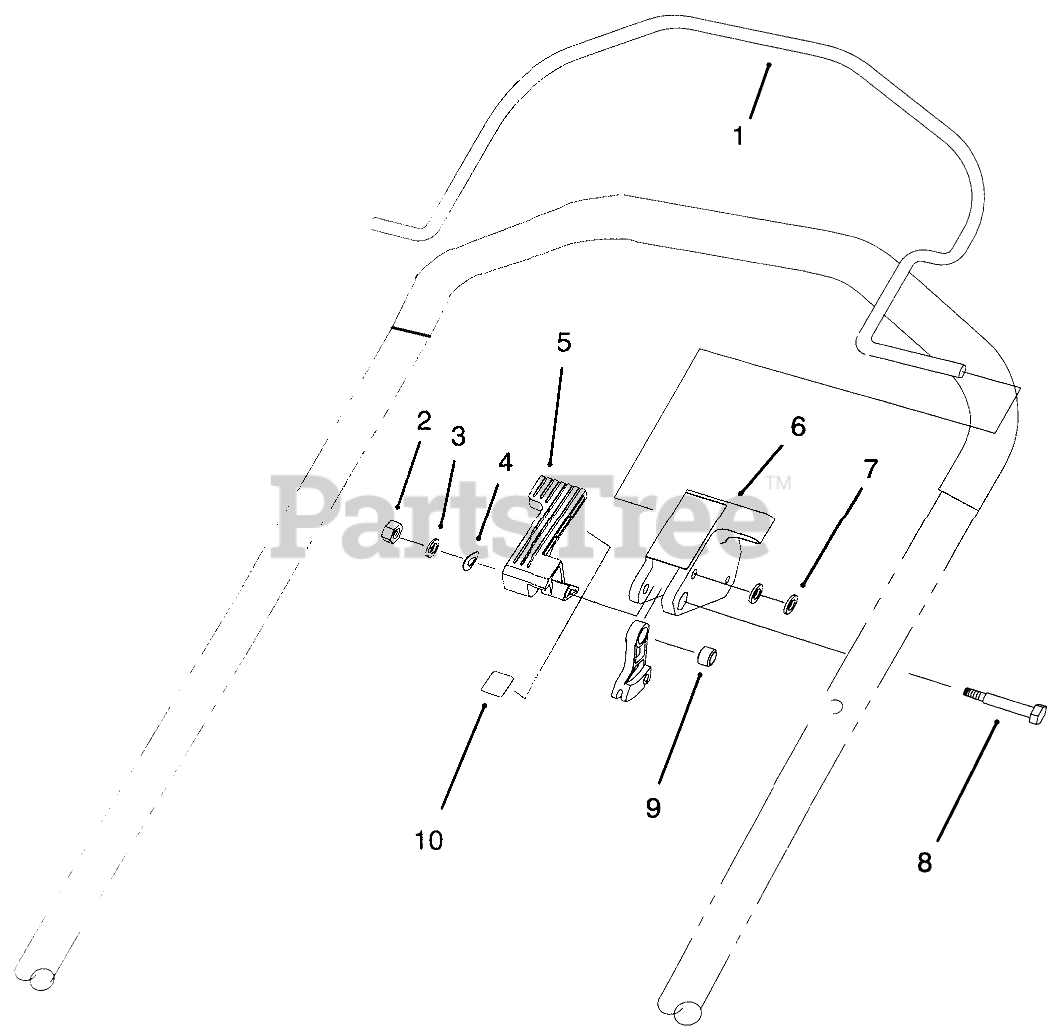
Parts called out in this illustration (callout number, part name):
1	BAIL - CONTROL
2	NUT-LOCK, NI
3	WASHER-PLAIN
4	WASHER - SPRING
5	LEVER - SHIFT
6	STOP - PIVOT, PLASTIC
7	WASHER-FLAT
8	SHOULDER BOLT
9	SPACER-LEVER, TRACTION
10	Decal-Traction
